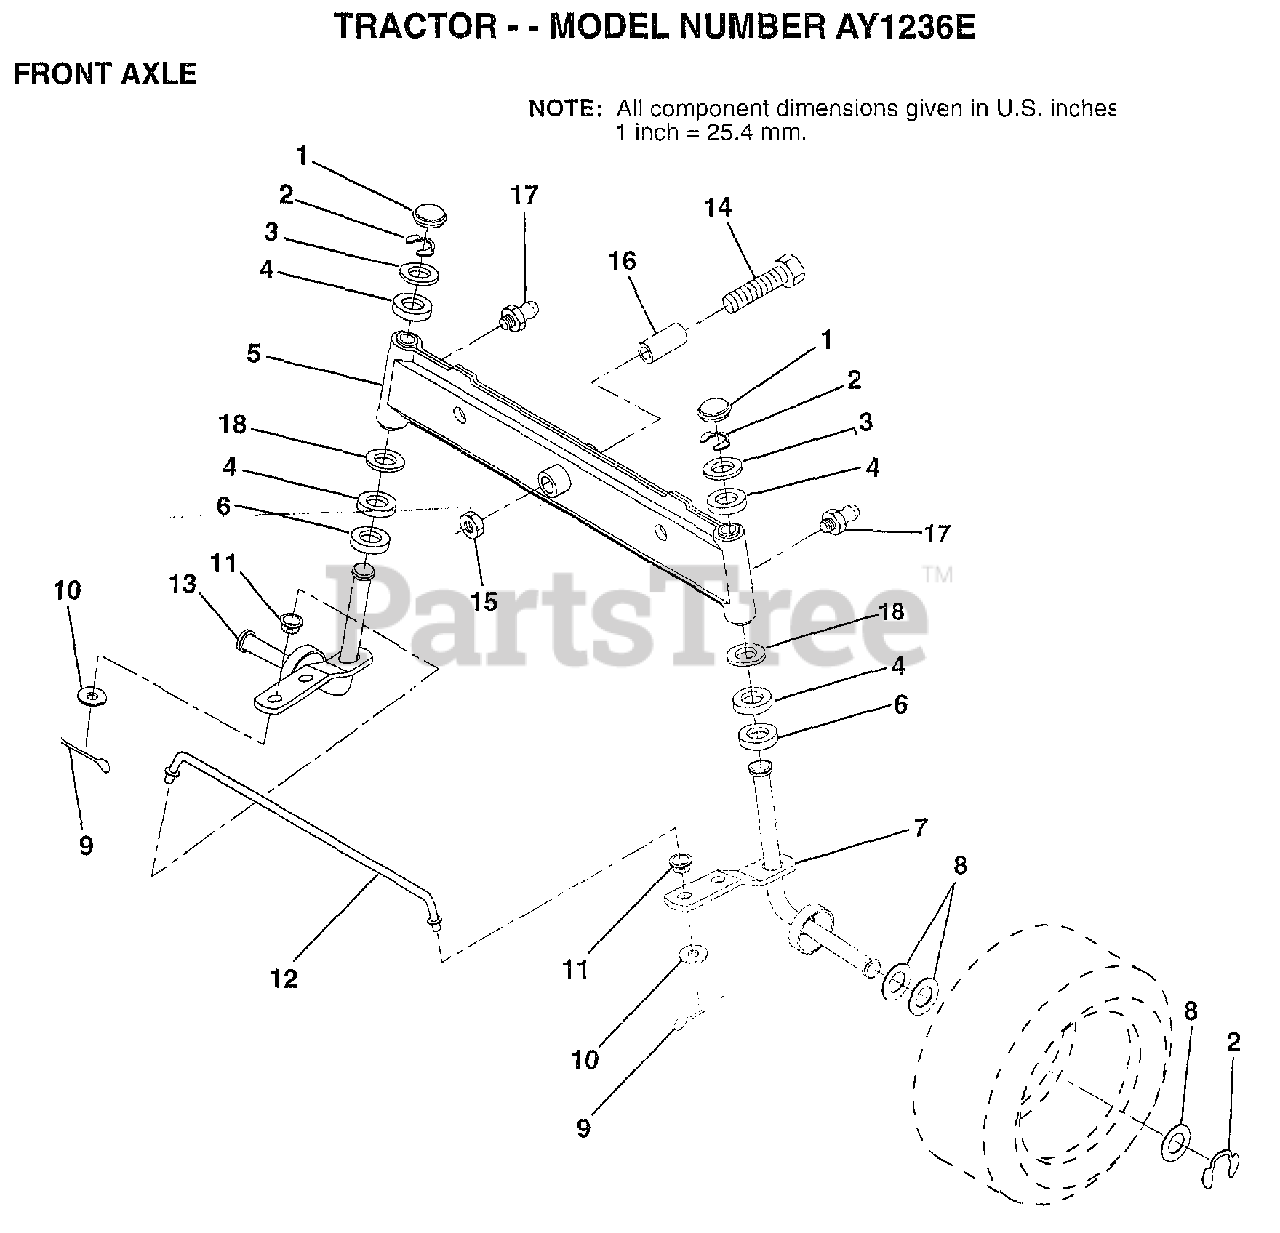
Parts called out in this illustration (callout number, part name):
1	CAP
2	RING
3	WASHER
4	COL. SRTG. BEAR.
5	AXLE ASM FRONT
6	WASHER .T
7	SPINDLE.ASSY.RH
8	WASHER
9	COTTER PIN
10	WASHER
11	BUSHING.DRAGLINK
12	TIE ROD
13	SPINDLE.ASSY.LH
14	BOLT HEX 5/8-11
15	"NUT-LOC,FLANGE LT"
16	BEARING
17	ZERK M
18	WASHER
